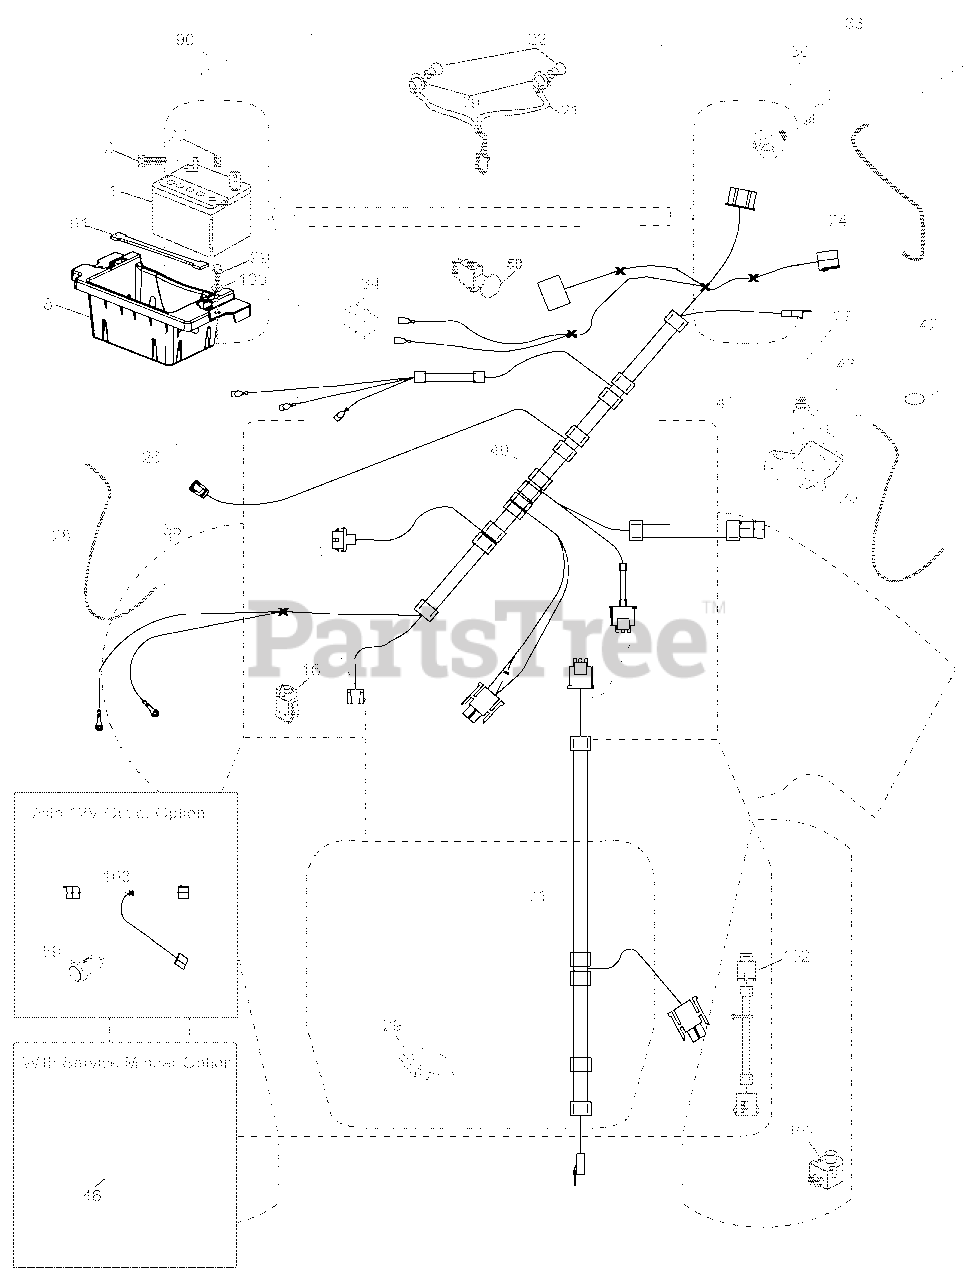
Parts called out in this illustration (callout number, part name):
2	BOLT.HEX.HD.1/4-20UNC X 3/4
8	BOX.BATTERY.MOUNT.FRONT.LT
16	SWITCH.INTERLOCK.NONO.GRAY
21	HARNESS ASM.LIGHT.22"(4152J)
22	BULB.LIGHT.#1156
24	CABLE.BTRY.PSWRE.DSH SOL.8"TEX
25	CABLE.STARTER.6GA.BL/RED.14.5"
26	FUSE.20 AMP.
27	Nut, Keps Hex 1/4-20 unc
28	CABLE.GROUND.21"BLK.6 GA.90T
29	SWITCH.SEAT.DELTA.OPC.9LB.
30	SWITCH.IGN.DLTA.P-IN.ROS
33	KEY/CHAIN.BLISTER PACK.GEN.CE
34	SWITCH.LIGHT/RESET.B/B/RED.
40	HARNESS.IGN.DASH.HUSQ/PRED.
41	Screw 1/4-20 x 1/2
42	COVER.TERMINAL.RED
43	SOLENOID.W/BRASS PLUNGER.2005
46	HOURMETER 401763
50	SWITCH.PTO.8 TERMINAL.BLACK
55	SCREW.5/16-18X3/4.SMGML.TAP/R
71	HARNESS.IGN.CHASSIS.TEX
79	SOCKET ASM.BULB.TWISTLOCK
81	RELAY HARNESS SEALED
91	STRAP.BATTERY.MOUNT.FRONT
99	SCREW.HEXWSH.THDROL.1/4-20X3/4
100	WASHER.9/32 X 7/8 X 16GA.
102	HARNESS.PIGTAIL.K46.TEX.ROS
105	SWITCH.REVERSE.TT.PEDAL CONTRO
